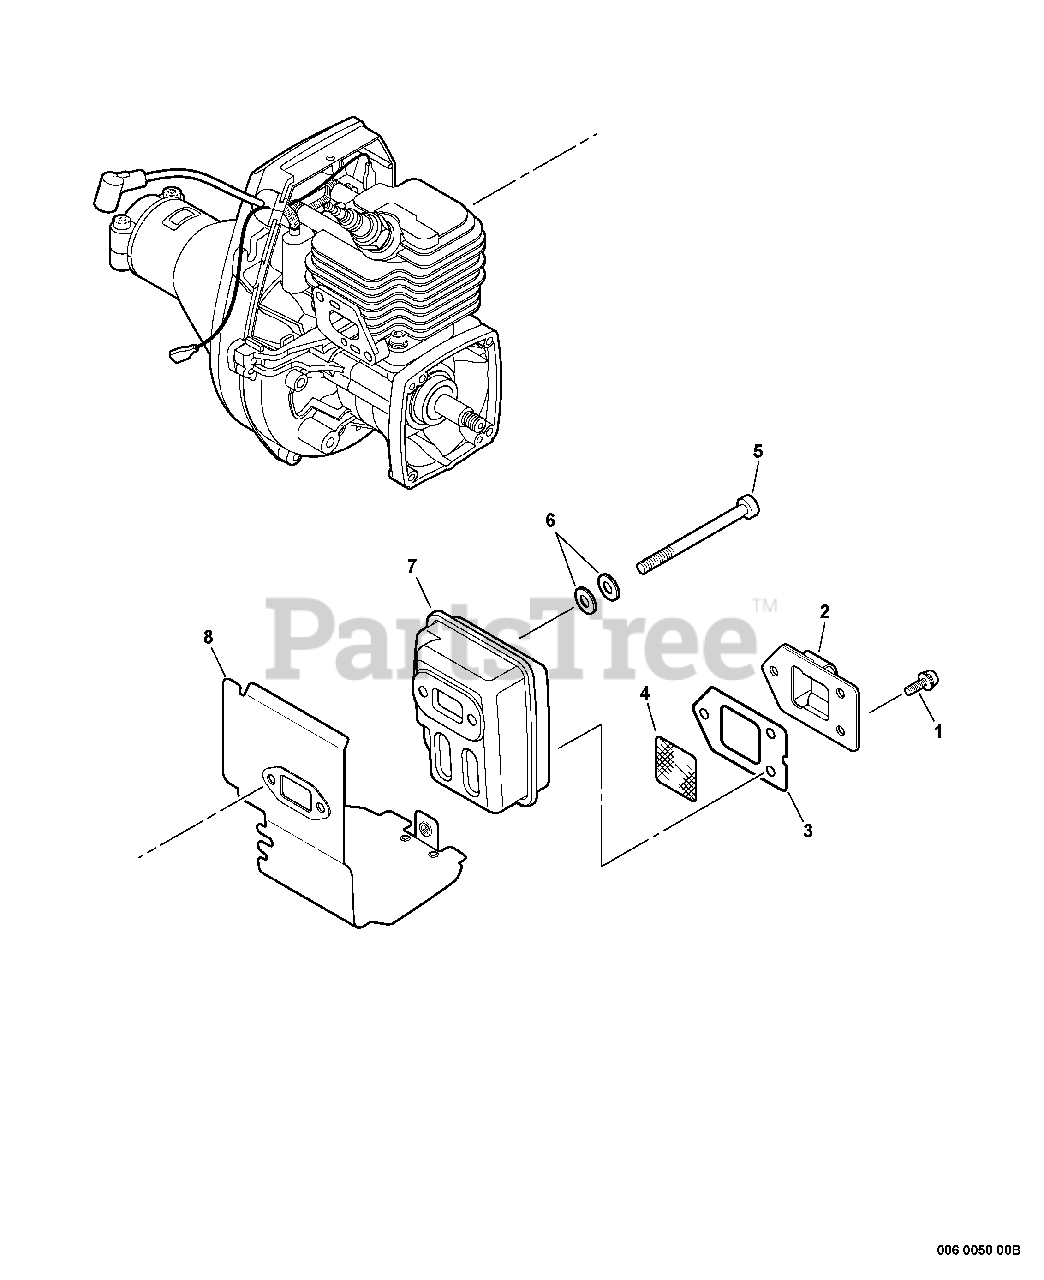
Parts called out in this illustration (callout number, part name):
1	SCREW - 4X10
2	GUIDE, EXHAUST
3	GASKET, EXHAUST
4	SCREEN, SPARK ARRESTOR
5	SCREW - 5X55
6	WASHER - 5
8	SHIELD, EXHAUST
